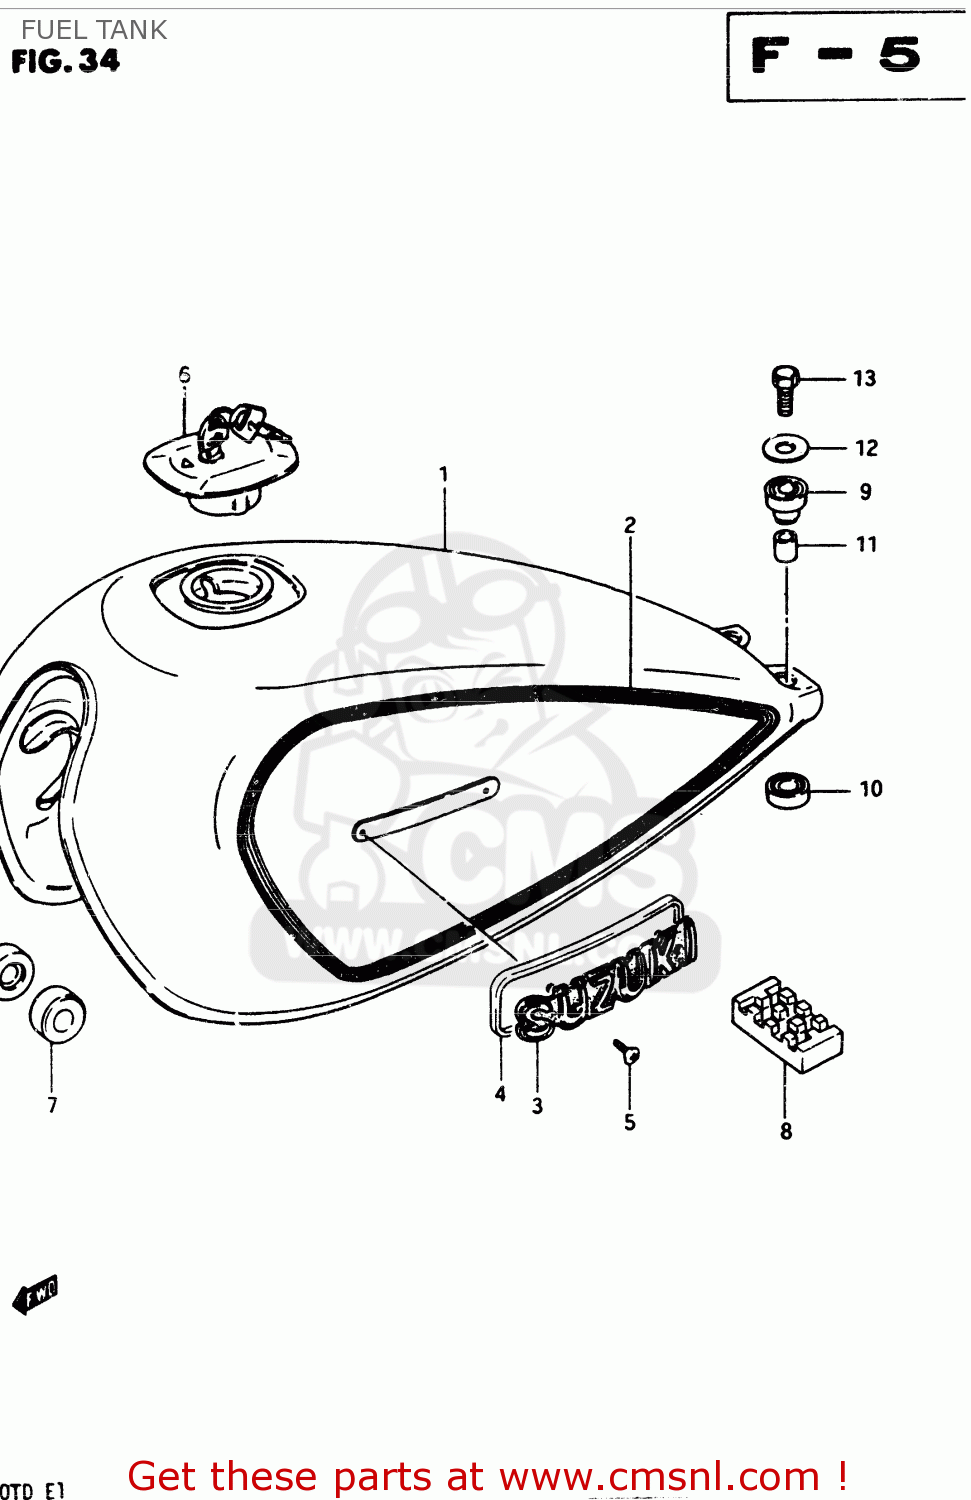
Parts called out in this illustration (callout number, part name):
1	TANK, FUEL (RED)
2	TAPE SET,FUEL TANK
3	EMBLEM,FUEL TANK
4	CUSHION, EMBLEM
5	SCREW 3X6
6	CAP SET,FUEL TANK
7	CUSHION
8	CUSHION
9	CUSHION
10	CUSHION
11	SPACER (6.4X9X20)
12	WASHER (6.5X24X1.6)
13	BOLT
